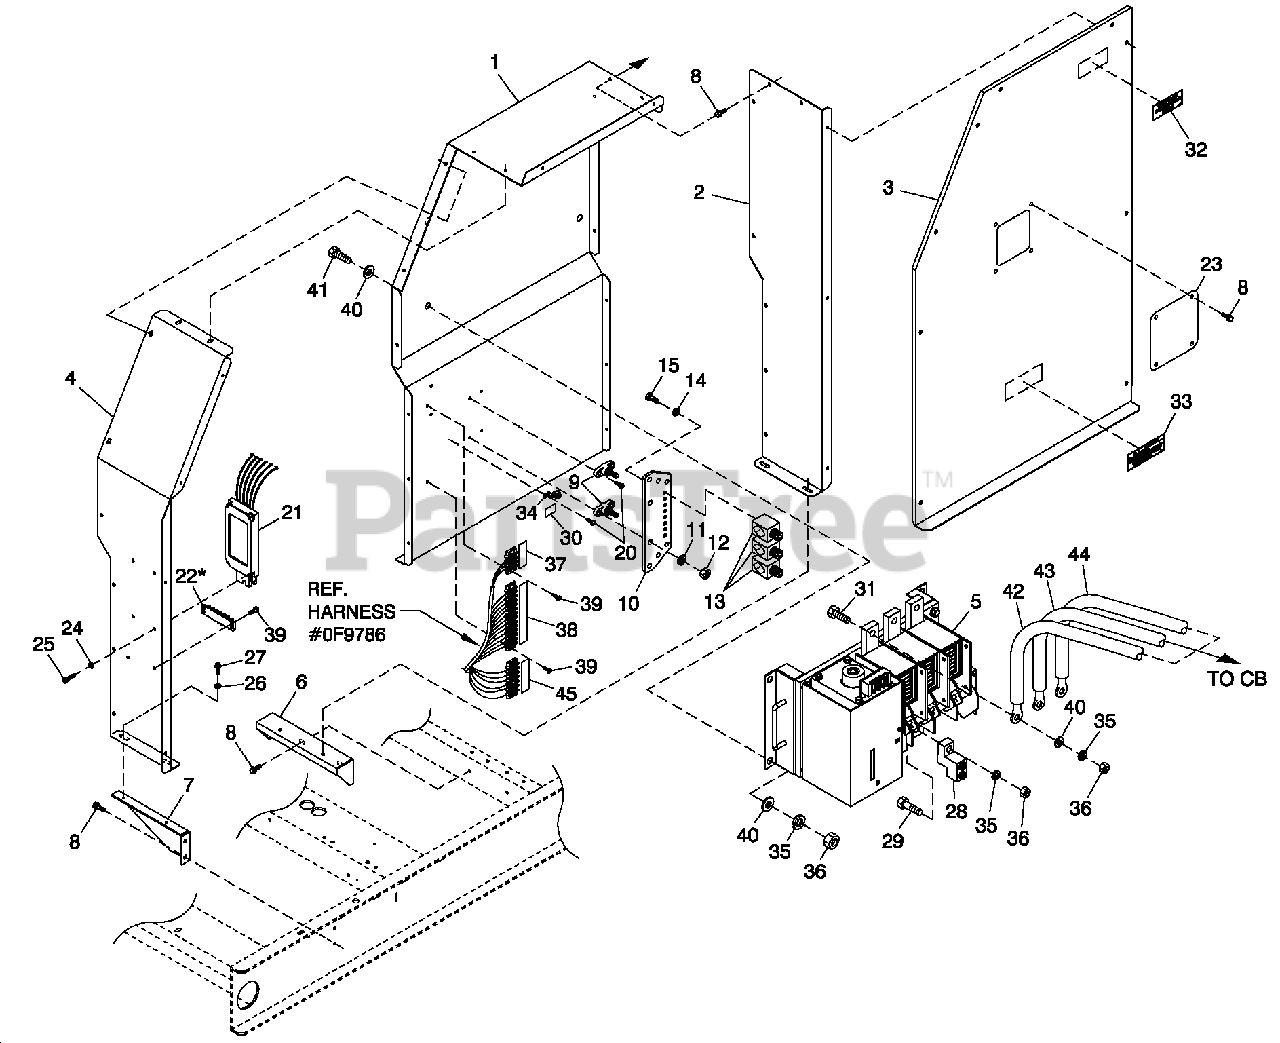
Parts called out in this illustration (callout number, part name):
1	PAN TRANS SWTCH CONN BOX
2	SIDE RH TRANS CONN BOX
3	COVER TRANS SWITCH CONN
4	SIDE LH TRANS CONN BOX
5	CONTACTOR 600A 3P 240CL12TR
6	MOUNT RH TRANS CONN BOX
7	SUPPORT CONBOX TRANSFER SWITCH
8	SCREW THF M6-1 X 16 N WAZ/JS
9	JUNCTION BLOCK 3/8-16
10	BUBAR NEUTRAL BLOCK (520/MAR)
11	WASHER LOCK 3/8
12	NUT HEX 3/8-16 STEEL
13	LUG SLDLSS 600/250-1/0 X 1/4-28
14	WASHER LOCK M6-1/4
15	SCREW HHC1/4-28 X 5 /8 .625TH
20	SCREW PHTT M5-0.8 X 16 ZYC
21	ASSY PCB 3PH VOLT DIV 208V L-L
22	BLOCK TERM 20A 6 X 6 X1100V
23	ACCESS COVER GALV
24	WASHER LOCK #8-M4
25	SCREW PPHM M4-0.7 X 10 SEMS
26	WASHER FLAT 1/4-M6 ZINC
27	SCREW HHTT M6-1.0 X 1 6 ZYC
28	LUG SLDLSS 500-+1X13/32 AL/CU
29	SCREW HHC M12-1.75 X 55 G10.9
30	DECAL GROUND LUG
31	SCREW HHC M12-1.75X 40 G8.8
32	DECAL CUSTOMER CONNECT INSIDE
33	DECAL DANGER HIGH VOLTAGE
34	LUG SLDLSS #6-14 X 13/64 CU
35	WASHER LOCK M12
36	NUT HEX M12-1.75 G8 YEL CHR
37	DECAL CUST CONN 120V UTILITY
38	DECAL CUSTOMER CONNECTION
39	SCREW PHTT #6-32 X 1/2 ZYC
40	WASHER FLAT M12
41	SCREW HHC M12-1.75X 25 G8.8
42	ASSY WIRE #285 E1 3/088.0"
43	ASSY WIRE #286 E2 3/0 88.0"
44	ASSY WIRE #287 E3 3/0 88.0"
45	DECAL GEMINI PLS CONNECTIONS
